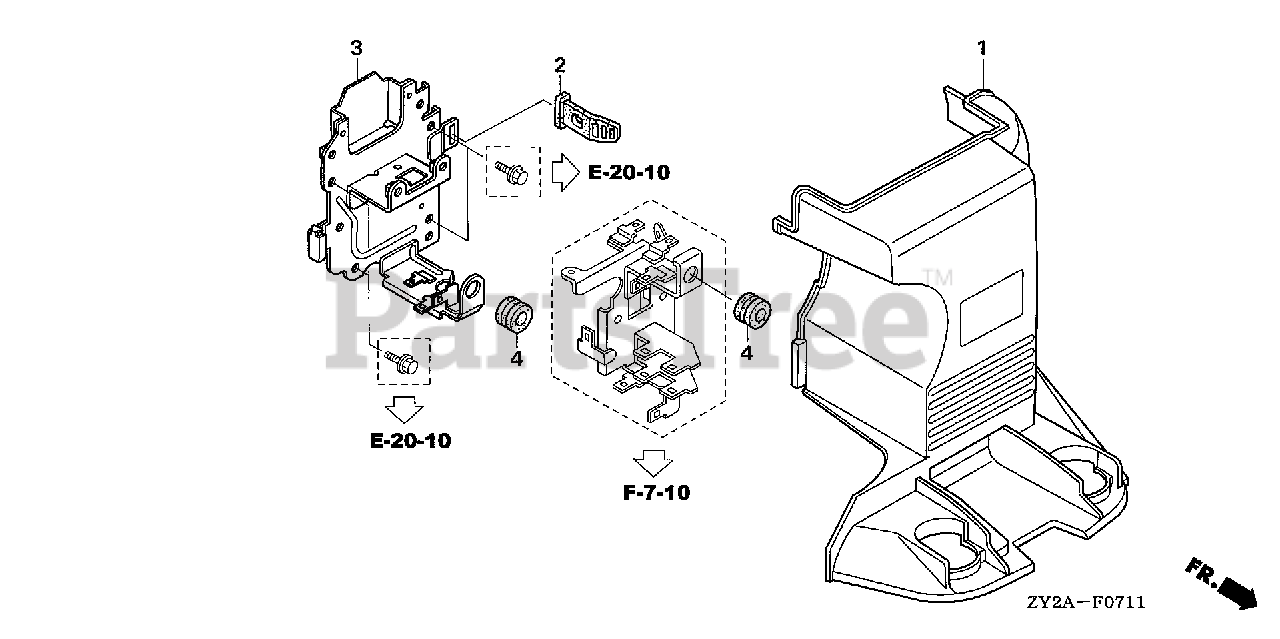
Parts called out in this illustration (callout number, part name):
1	COVER, ELECTRIC PARTS
2	BELT, COVER
3	BRACKET, ELECTRIC PARTS
4	RUBBER, TANK CUSHION
